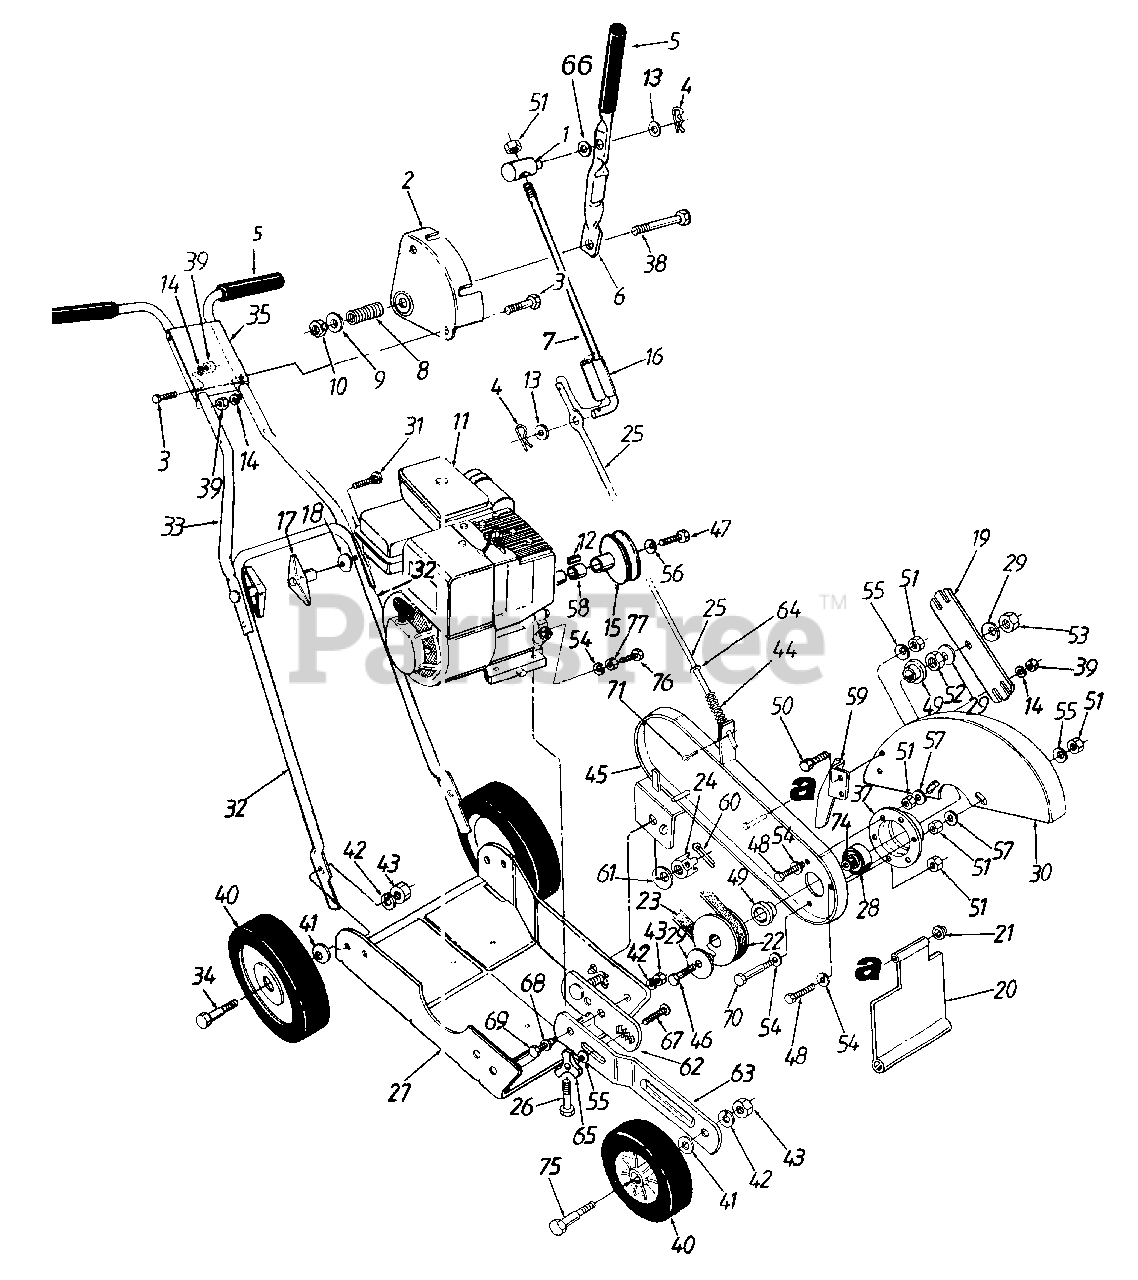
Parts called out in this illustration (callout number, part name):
1	Ferrule
4	Hairpin Clip
5	Foam Grip
7	Upper Clutch Rod
8	Compression Spring 1.38" Lg.
9	Fl-Wash. .344" I.D.
10	Hex L-Nut 5/16-18 Thd.
11	Engine
12	Sq. Key 3/16" x 1" Lg.
13	Fl-Wash. .344" I.D.
14	L-Wash. 1/4" I.D.
15	Engine Pulley
16	Clutch Rod Lock
17	Wing Nut Ass'y.
18	Saddle Wash. .32" I.D. x .937" O.D.
20	Edger Guide Flap
21	Push Cap
22	3/8" "V"-Pulley
23	"V"-Belt
24	Hex Slotted Nut 1/2-20 Thd.
25	Lower Clutch Rod
26	Hex L-Wash. TT-Tap Scr. 3/8-16 x 1" Lg.
29	Bell-Wash. 5/8" I.D. x 1-1/4" O.D.
38	Hex Bolt 5/16-18 x 2" Lg.
39	Hex Nut 1/4-20 Thd.
40	Wheel Ass'y.
41	Bell-Wash 38" I.D. x .88" O.D.
42	L-Wash. 3/8" I.D.
43	Hex Nut 3/8-16 Thd.
44	Comp. Spring 2" Lg.
47	Hex Bolt 3/8-24 x 1.5" Lg. (Gr. 5)
48	Hex Cap Bolt 5/16-18 x 1-1/4" Lg.
49	Shld. Spacer .626" I.D.
50	Hex Bolt 1/4-20 x .5" Lg.
51	Hex Nut 5/16-18 Thd.
52	Hex Jam Nut 5/8-18 Thd.
53	Hex Ins. L-Nut 5/8-18 Thd.
54	L-Wash. 5/16" I.D.
55	Bell-Wash. .345" I.D. x .88" O.D.
56	Bell-Wash. .396" I.D. x 1.14" O.D.
57	Fl-Wash. .312" I.D. x .75" O.D.
58	Spacer .748" I.D. x .985" O.D.
61	Bell-Wash. .515" I.D. x 1.14" O.D.
65	Hand Knob
66	Spring Wash. .32" I.D.
67	Carr. Bolt 5/16-18 x 1" Lg.
68	Spacer .383" I.D. x .503" O.D.
69	Hex Bolt 318-16 x 1" Lg.
70	Shld. Bolt 5/16-18 x 1.27" Lg.
71	Cotter Pin 1/8" Dia. x 1" Lg.
74	Fl-Wash. .64" I.D. x 1.12" O.D.
75	Shld. Bolt .498" Dia. x 1.64" Lg.
76	Hex Bolt 5/16-24 x 2.75" Lg. (Gr. 5)
77	Hex Nut 5/16-24 Thd."
